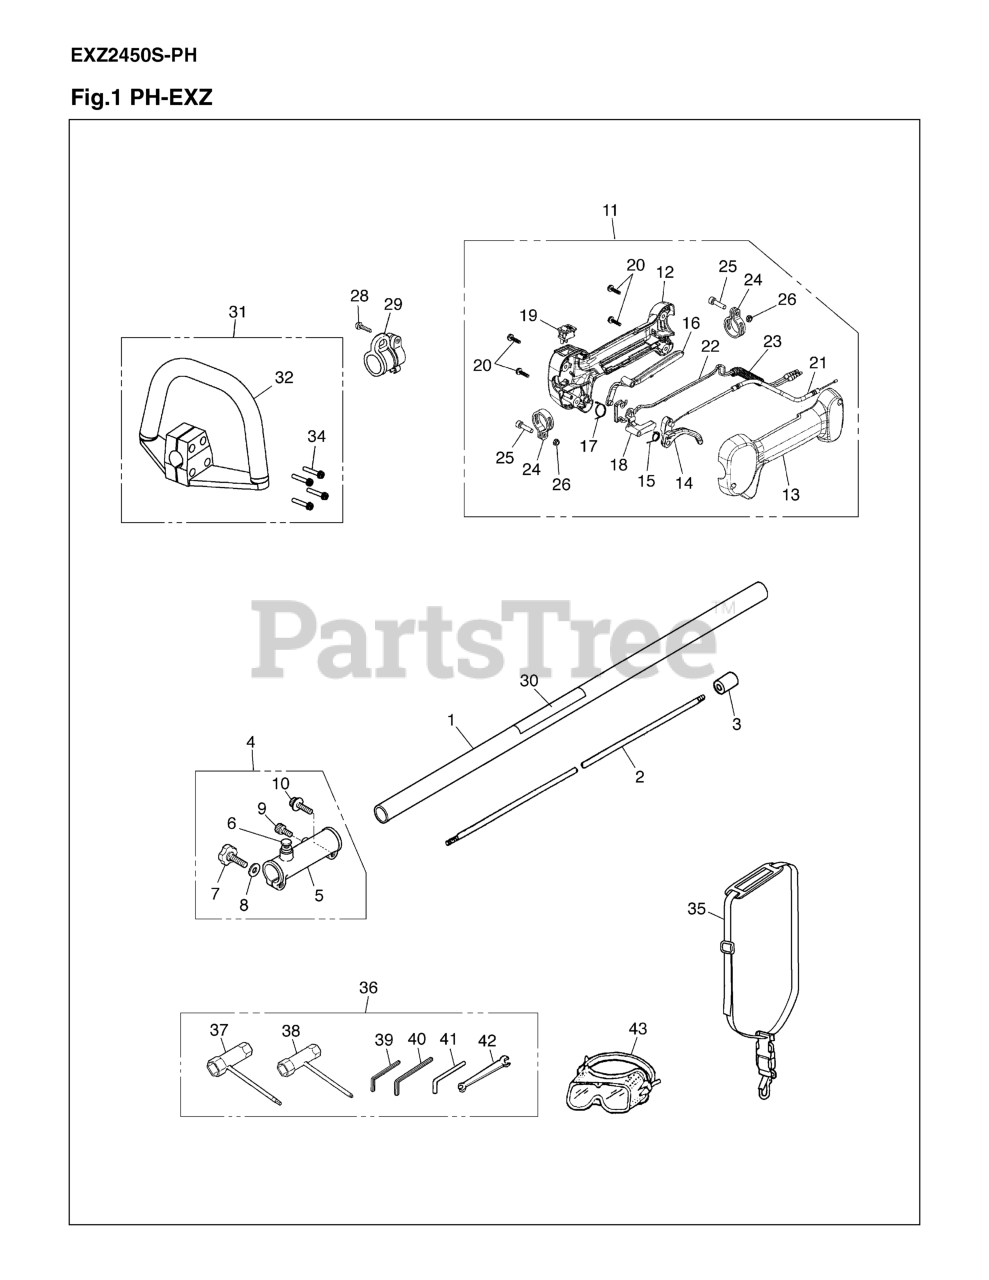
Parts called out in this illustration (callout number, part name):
1	PIPE COMP
2	SHAFT
3	SPACER
4	JOINT, PIPE ASSY
5	JOINT
6	STOPPER COMPLETE
7	BOLT, KNOB
8	WASHER
9	BOLT
10	BOLT
11	GRIP ASSY
14	LEVER, THROTTLE
15	SPRING, THROTTLE
16	LEVER, SAFETY
18	LEVER, JOINT
19	SWITCH
20	SCREW
21	CABLE COMP
22	CORD COMP
23	TUBE
25	BOLT TORX
28	HANGER COMP.
30	PLATE-NAME
31	HANDLE ASSY
32	HANDLE COMP
34	SCREW
35	STRAP ASSY
36	TOOL SET
37	SOCKET
38	SOCKET
40	WRENCH (TOOL)
41	BAR
42	SPANNER
43	GOGGLE
